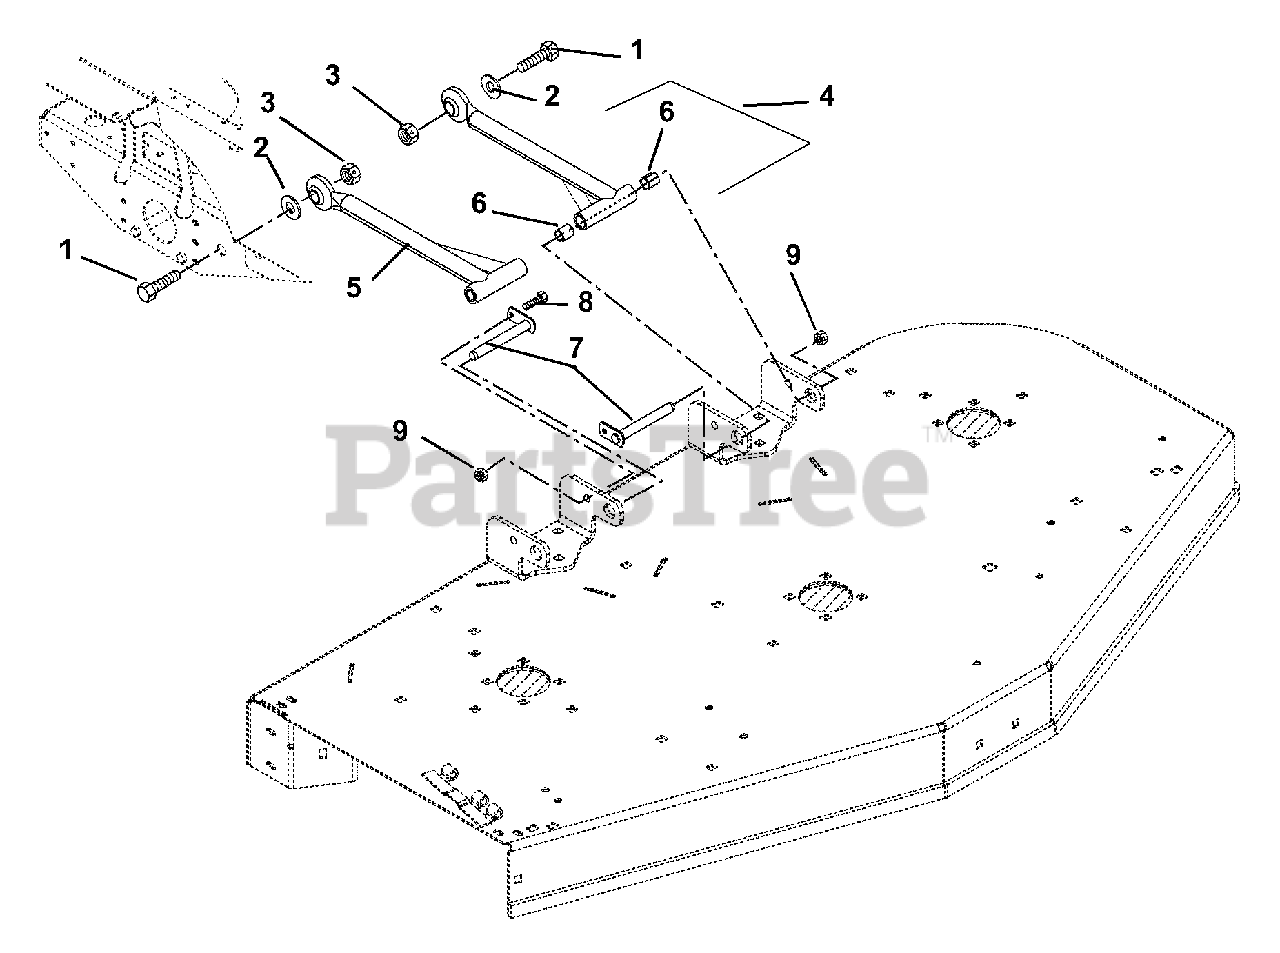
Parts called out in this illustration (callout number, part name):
1	Bolt, Hex .875-9 x 3.00
2	Bushing, Sleeve .875 x 1.25 x .531
3	Nut, Locking Center .875-9
4	Assembly, Mower Mounting
5	Arm, Mower Mounting
6	Bearing, .75 x .875 x 1.00
7	Weldment, Mower Mounting Pin
8	Bolt, Hex .38-16 x 1.00
9	Nut, Nyloc Flange .38-16
